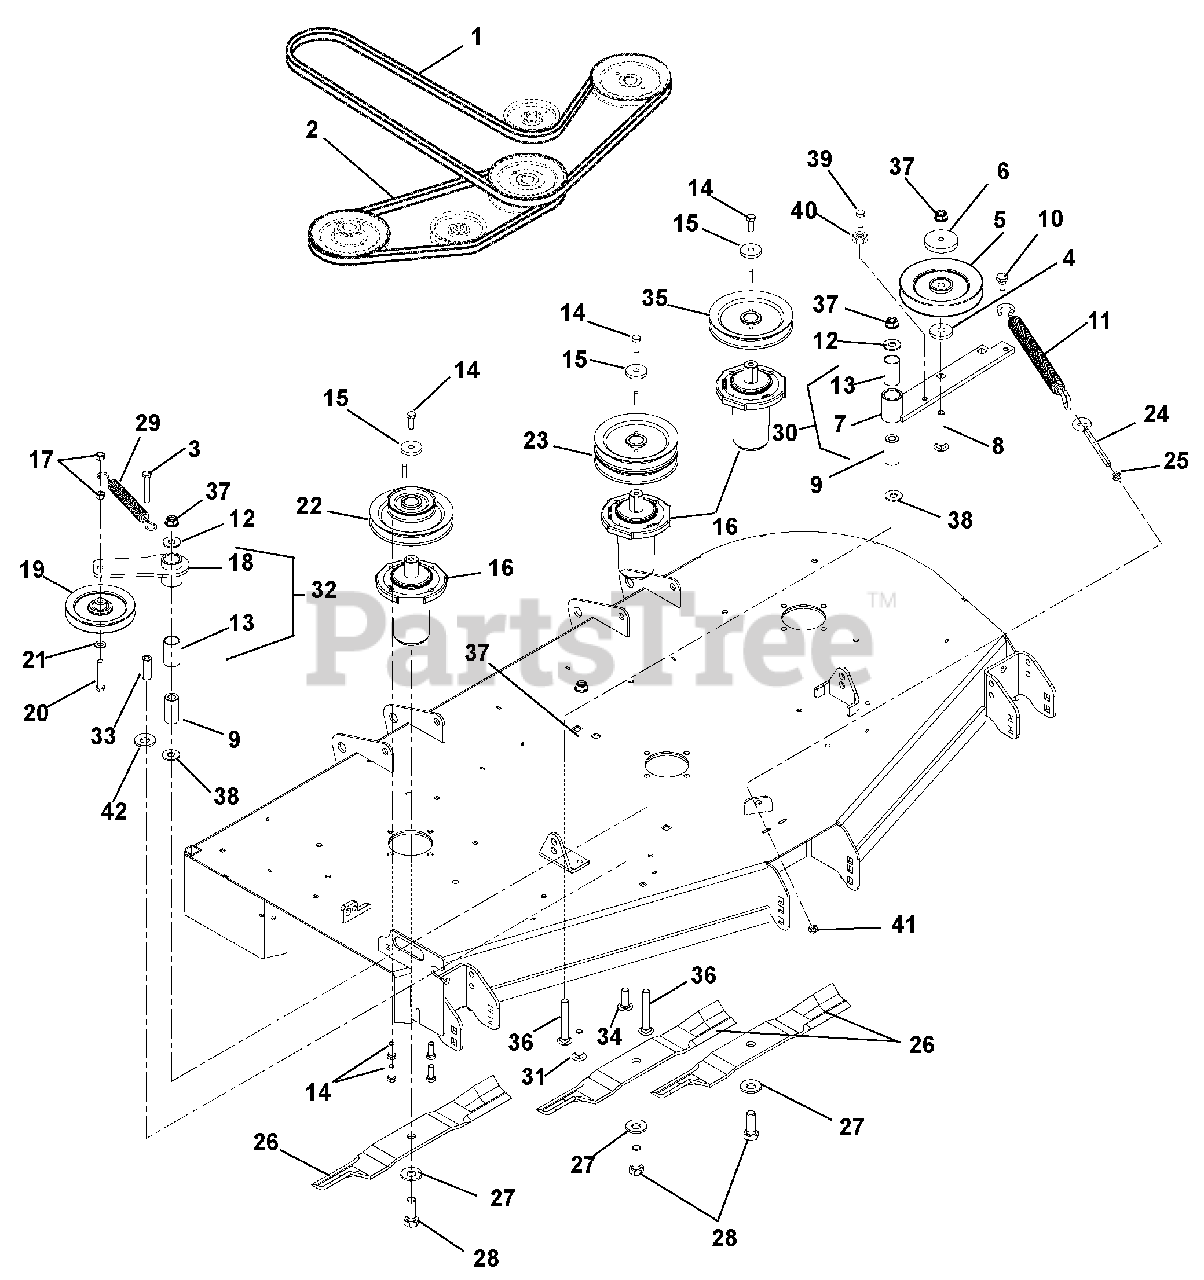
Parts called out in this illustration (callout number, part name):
1	Belt, BB 130.00 Wrapped Hex (991091, 084)
2	Belt, B 63.00 Raw Cogged (991091, 084)
3	Bolt, Hex .38-16 x 1.50 Grade 5
4	Bushing, Spacer .502 x .997 x .50
5	Sheave, .50" ID x 6.00" OD V-Idler
6	Cap, Idler Bearing Sealing
7	Idler Pivot Arm Weldment – Black
8	Bolt, Round Head Square Neck .50-13 x 3.00 Grade 5
9	Bearing, Pedestal
10	Bolt, Shoulder EP .38-16 x .30 Hex
11	Spring, Extension (Deck Idler)
12	Washer, Flat Steel .563 x 1.38 x.109
13	Bushing, 1.00 x 1.125 x 1.936
14	Bolt, Hex .38-16 x 1.00
15	Washer, Flat Steel .406 x 1.50 x .245
16	Spindle Assembly
17	Nut, Locking Center .38-16
18	Idler, Pivot Arm
19	Sheave, .38" ID x 5" OD V-Idler
20	Bolt, Hex .38-16 x 2.25
21	Washer, Flat Steel .406 x .812 x .065
22	Sheave, Double 1.0' ID x 6.75" x 4.35" OD (991091, 084)
23	Sheave, Double 1"ID x 6.75"OD (991091, 084)
24	Bolt, .38-16 x 4.00 .62 Diameter Eye
25	Nut, Hex Jam .375-16
26	Blade, 20.5" (991084)
27	Washer, Bellville .63 x 1.625 x.14
28	Bolt, Hex .62-18 x 1.75 Grade 8
29	Spring, Extension
30	Assembly, PTO Idler Pivot Arm (Includes item 7 and item 13)
31	Bolt, Round Head Square Neck .50-13 x 1.5, Full Thread, Grade 5
32	Assembly, Idler Pivot Arm (Includes item 13 and item 18)
33	Nut, Coupling .375-16 x 1.75
34	Bolt, Round Head Square Neck .38-16 x 1.00
35	Sheave, Single 1" ID x 6.75" OD (991091, 084)
36	Bolt, Round Head Square Neck .50-13 x 3.50 Grade 5
37	Nut .50-13 Nyloc Flange
38	Washer, Flat .640 x 1.75 x .250
39	Bolt, Hex .38-16 x 2.75 Grade 5
40	Nut, Hex .38-16
41	Nut, Locking Center Jam .375-16
42	Washer, Flat Steel .531 x 1.06 x .095 YZ
